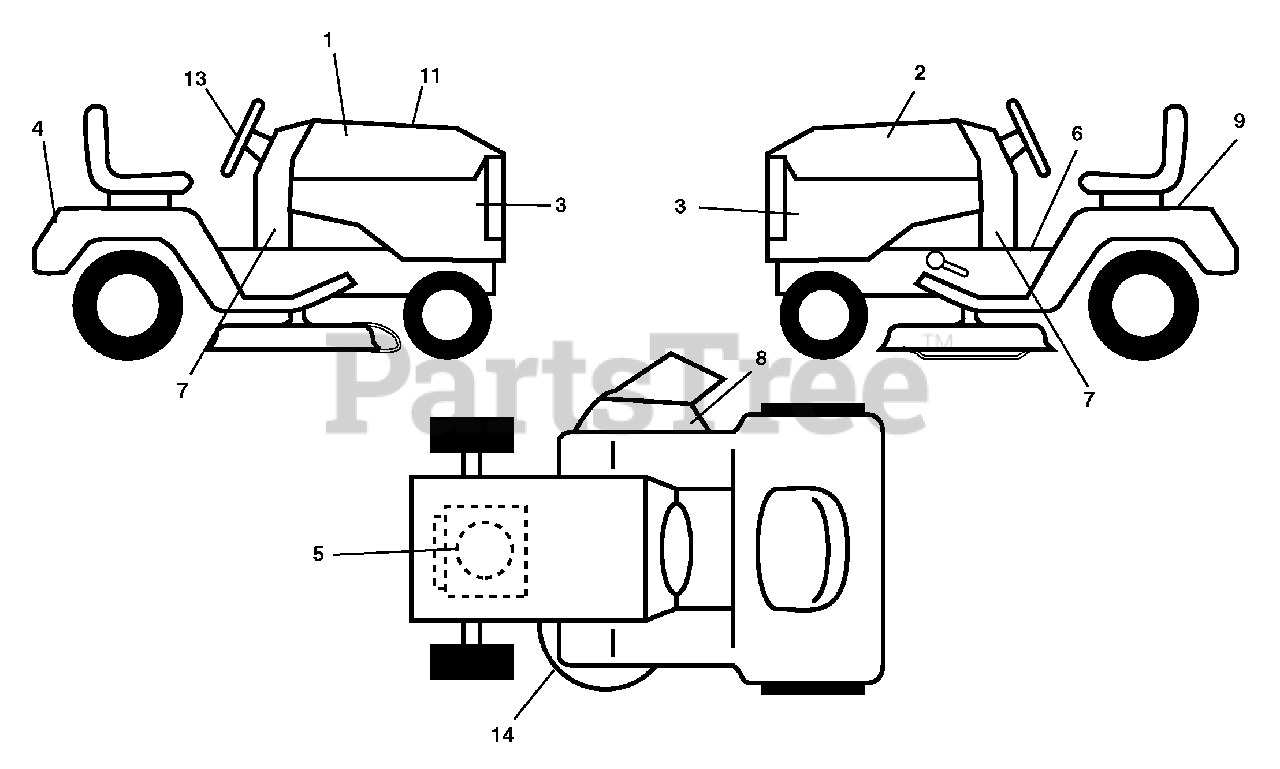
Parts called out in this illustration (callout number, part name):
1	Decal, Hood RH
2	Decal, Hood LH
3	Decal, Side Panel
4	Decal, Fender
5	Decal, Engine
6	Decal, Fender Operator's
7	Decal, Lower Dash
8	Decal, Warning
9	Decal, Battery Dnge/Poi
11	Decal, Replacement
13	Decal, Steering Wheel
14	Decal, Mower Schematic
